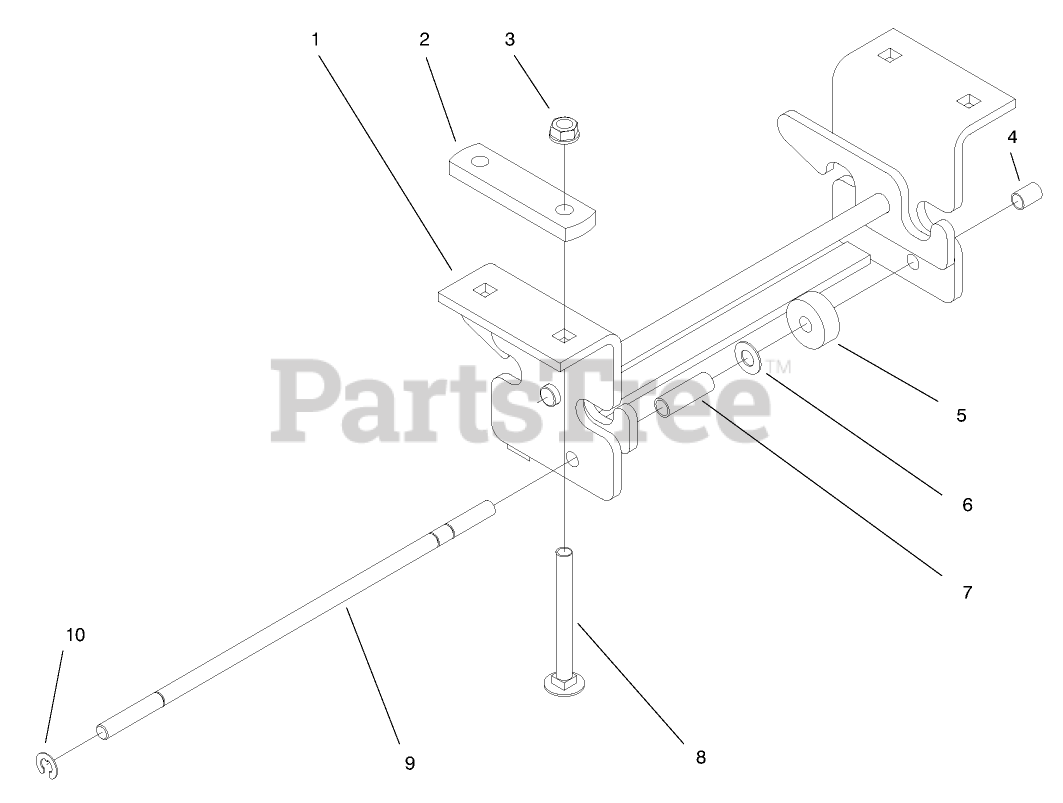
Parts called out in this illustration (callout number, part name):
1	Mounting Bracket ASM
2	BRACKET-REAR LINK MOUNTING
3	NUT-LOCK, SIDE
4	CAP-ROD, PLUNGER
6	WASHER-FLAT
7	SPRING
8	SCREW-CARR
9	ROD-LATCH, HITCH
10	RING-RETAINING
